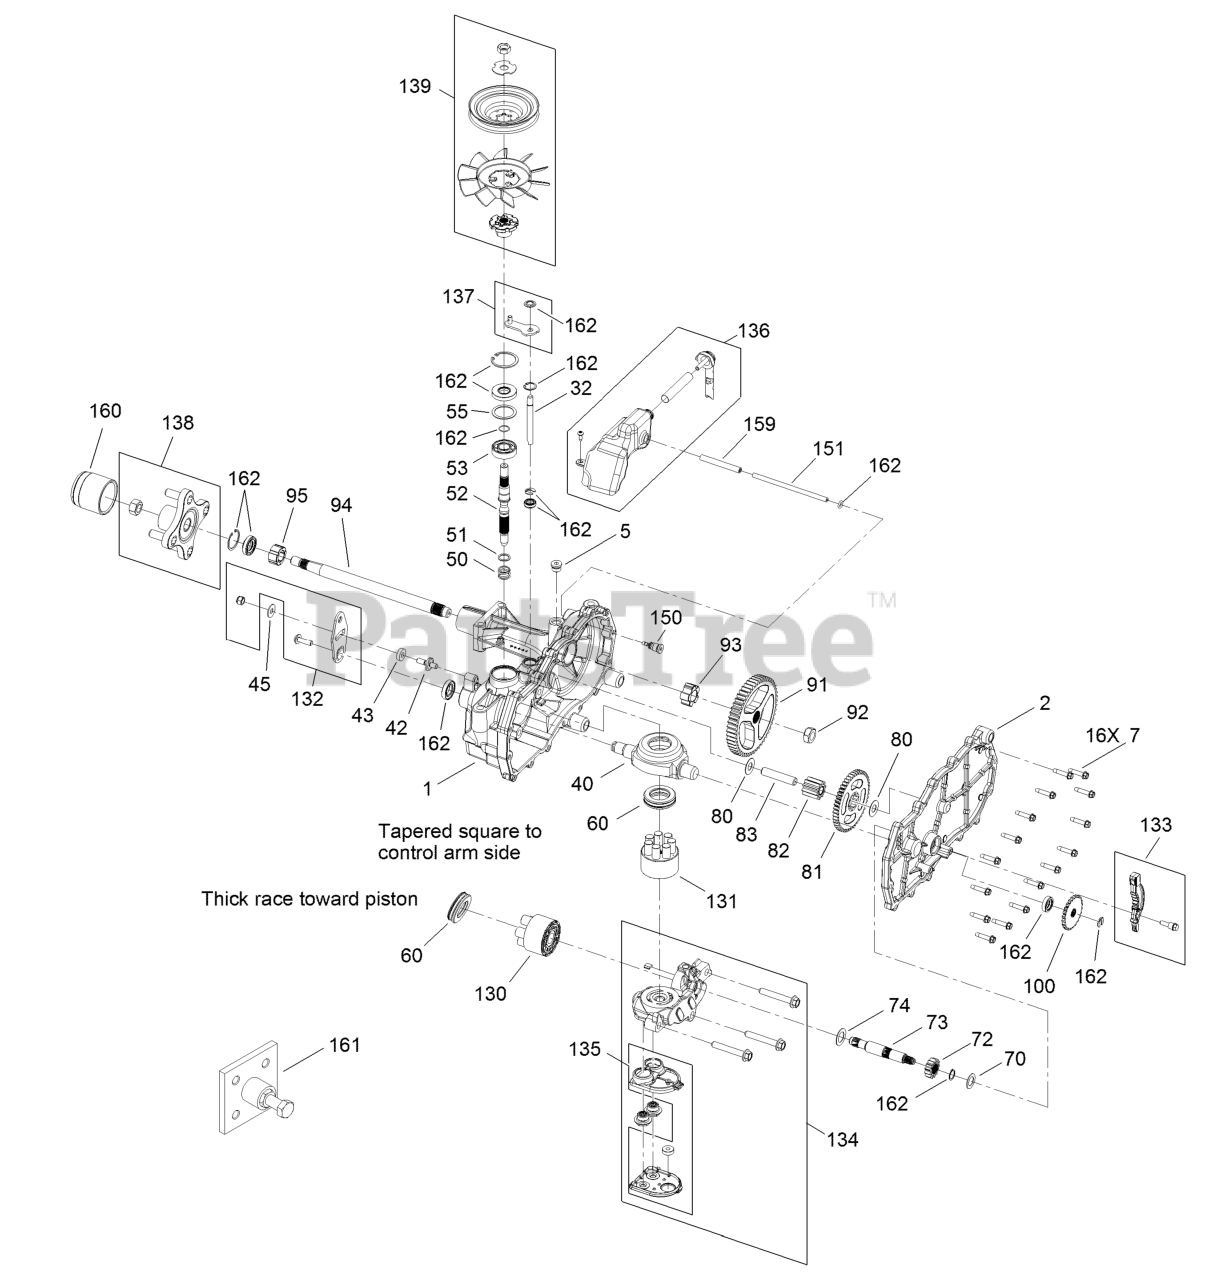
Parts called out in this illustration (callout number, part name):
1	MAIN HOUSING ASM
2	HOUSING SIDE KIT
5	PLUG-THREAD, STRAIGHT
7	SCREW-HHF
32	ROD-BYPASS
40	SWASHPLATE-TRUNNION
43	PUCK-FRICTION
52	SHAFT-INPUT
53	BEARING-BALL
60	BEARING-THRUST
70	WASHER-FLAT
72	GEAR-PINNION, 13T
73	SHAFT-MOTOR
80	Washer
81	GEAR-10T/48T
82	GEAR-JACKSHAFT, 10T
83	PIN-JACKSHAFT
91	GEAR-BULL
93	BUSHING-INBOARD
94	SHAFT-AXLE
95	BEARING-SLEEVE
100	DISC-BRAKE, COG
130	CYLINDER BLOCK KIT
131	PUMP BLOCK ASM
132	CONTROL ARM KIT
133	BRAKE ARM KIT
134	CENTER SECTION FILTER KIT
135	FILTER KIT
136	RH EXPANSION TANK KIT
137	BYPASS KIT
138	HUB KIT
139	FAN PULLEY KIT
150	FITTING-SAE
159	CASE-TUBE
160	CAP-AXLE
162	SEAL AND RING KIT
